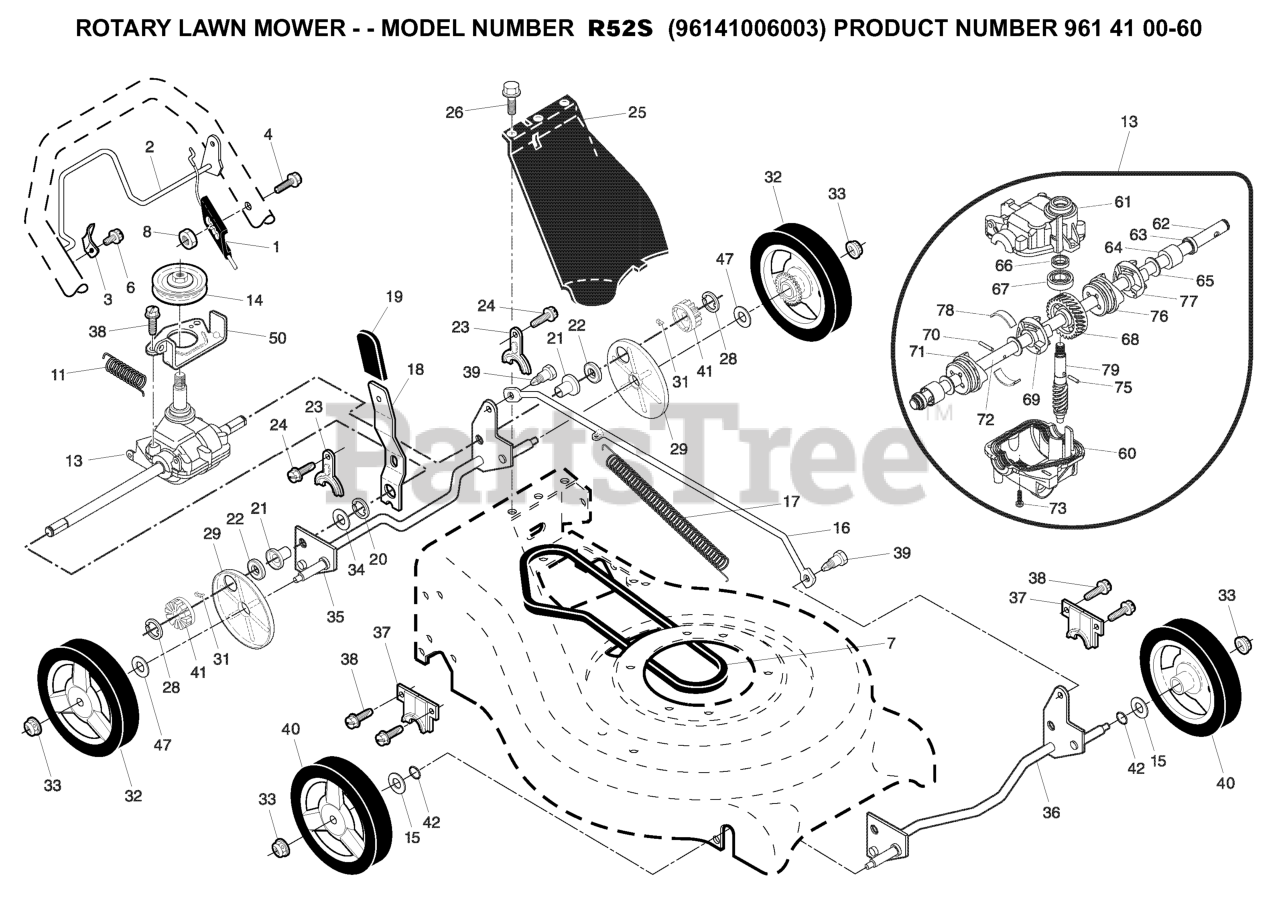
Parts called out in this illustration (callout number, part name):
3	DOWNSTOP BRACKET
7	RP.BELT.DRIVE.RGD.SS.WALK
8	NUT.HEX.FLANGE.1/4
13	TRANSMISSION.21.RWGD.AUTO.SP
14	PULLEY.RGD.SS.3.25OP
15	WASHER.FLAT.1/2
16	ROD.CONNECTING.SPT.BLACK
17	SPRING EXTENSION
18	SPRING.SELECTOR.SPT.21
19	KNOB.EXT.ERGO.BLACK
21	BEARING SUPPORT
22	BEARING
23	BRACKET
25	COVER.DRIVE.21.RWGD.MO
28	E-RING 7/16 RE
29	COVER.DUST.WHEEL
31	PAWL, DRIVE
32	WHEEL & TIRE ASSY, REAR
33	NUT.HEX.FLANGE.3/8-16.LO(3 2)
35	SHAFT ASSY REAR
36	SHAFT ASSY, FRONT
37	RETAINER.FRONT.SHAFT
39	SHOULDER BOLT SEMI GIMLET PT.
40	WHEEL & TIRES ASSY, FRONT
41	PINIION.14.TOOTH.RGD
42	O-RING..070X.487.NEOPRENE
47	WASHER FLUT
50	BRACKET.BELT.KEEPE/AUT*SUBS/2*
60	CASE, LOWER
61	CASE UPPER
62	SHAFT OUTPUT LONG
63	SEAL.OUTPUT.SHAFT
66	SEAL INPUT SHAFT
68	GEAR 28 TEETH
69	DOG.FIXED.LH.32003
70	PIN 7 33732
71	DOG.MOVEABLE.LH.32005
72	SHAFT OUTPUT SHORT (12294)
75	PIN 3.50.337 - 33733
76	DOG.FIXED.RH.32004
77	DOG.MOVEABLE.RH.32006
78	SPRING LEAF
79	SHAFT WORM
